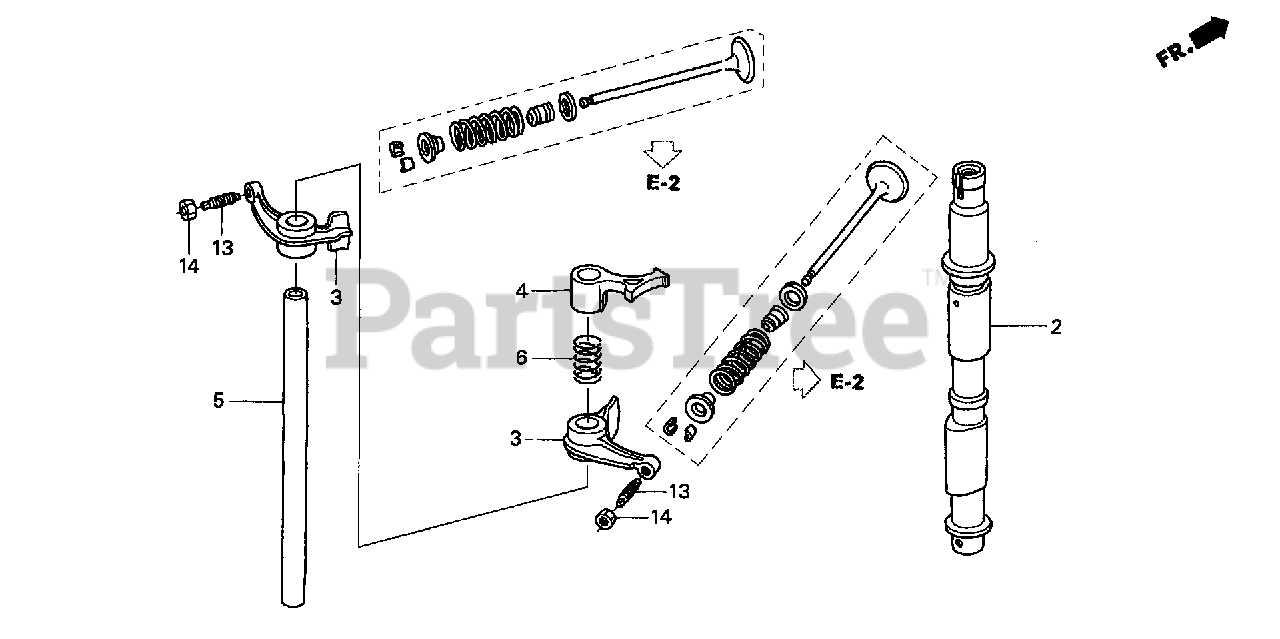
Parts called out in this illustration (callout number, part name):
3	ARM, VALVE ROCKER
4	ARM, FUEL PUMP ROCKER
5	SHAFT, ROCKER ARM
6	SPRING, ROCKER ARM
13	SCREW, TAPPET ADJUSTING
14	NUT, TAPPET ADJUSTING
